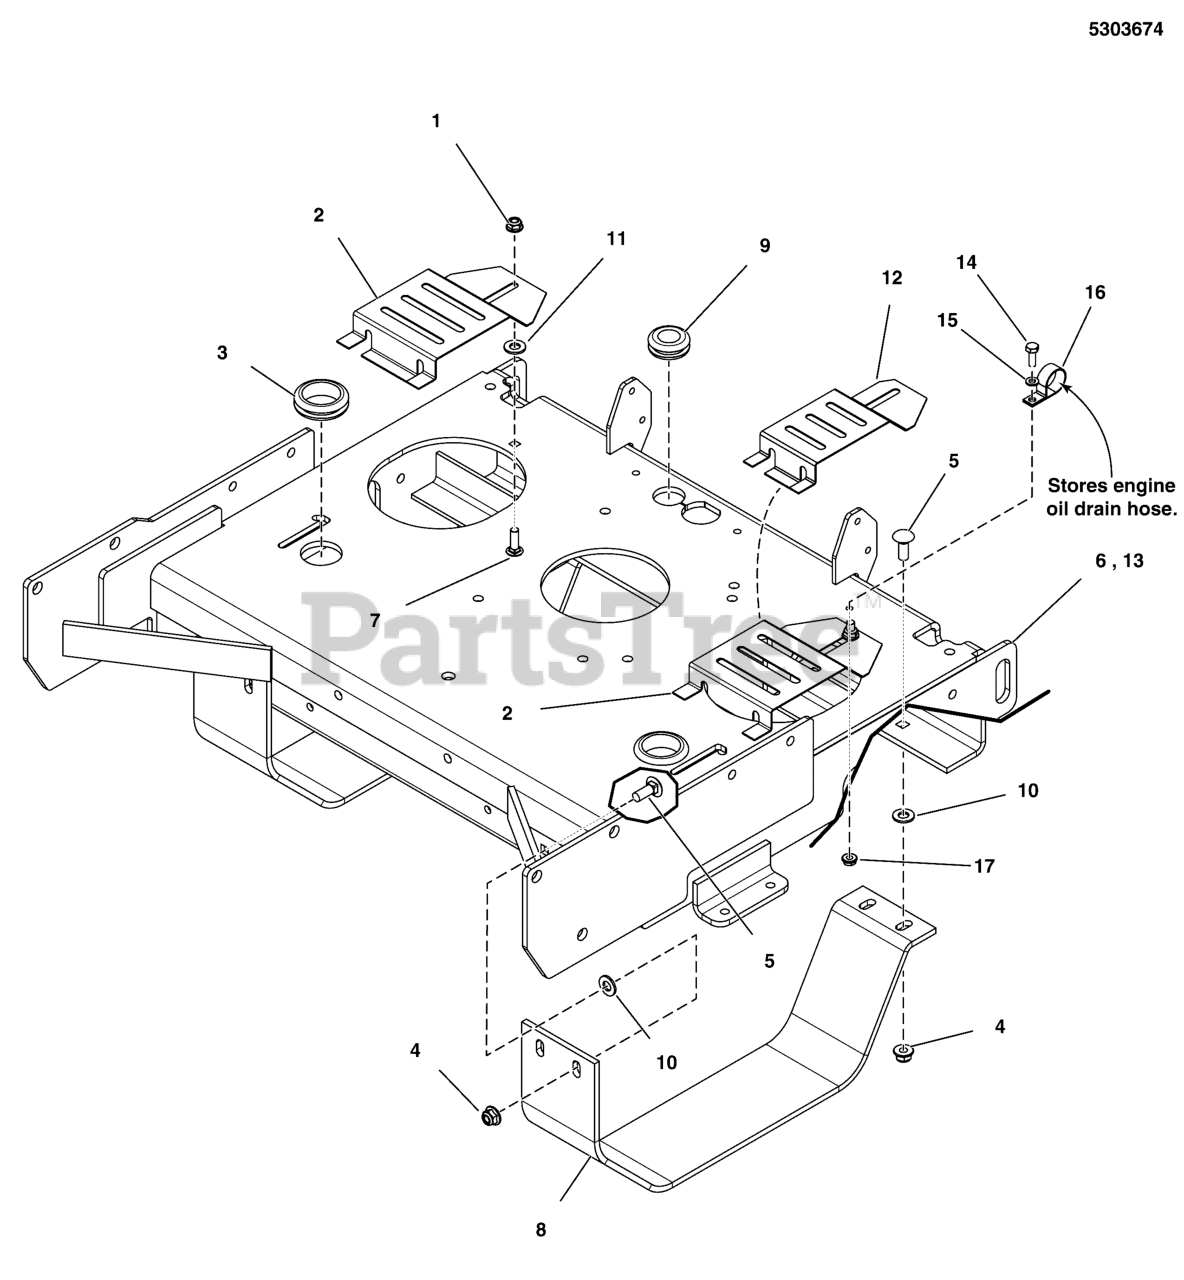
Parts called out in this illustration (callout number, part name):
1	NUT, 5/16-18 HEX NYLOCK FLANGE
2	PLATE, FAN GUARD - BLK
3	GROMMET, 1-1/2" ID FOR 1/4" METAL
4	NUT, 3/8-16 HEX NYLOCK FLANGE
5	BOLT,3/8-16X1.000,RND HD CRRG,ZINC/CLEAR
6	WELD, ENGINE DECK, WALK BEHIND - RED
7	BOLT, 5/16-18 X 1, CARRIAGE
8	PLATE, TRANS GUARD, SW30 - BLK
9	GROMMET, 7/8"ID, 1/4" THICK STK
10	3/8 PUSHNUT BOLT RETAINER
11	5/16 PUSH-ON NUT RETAINER, STL, CZ
12	PLATE, FAN GUARD, BV, LH - BLK
13	WELD, ENGINE DECK, W35 - RED
14	BOLT, 1/4-20 X 3/4 GD5 CZ
15	WASHER, 1/4 SAE
16	CLAMP, VINYL INSULATED, 1.00
17	NUT, 1/4-20 HEX SERR. FLANGE
